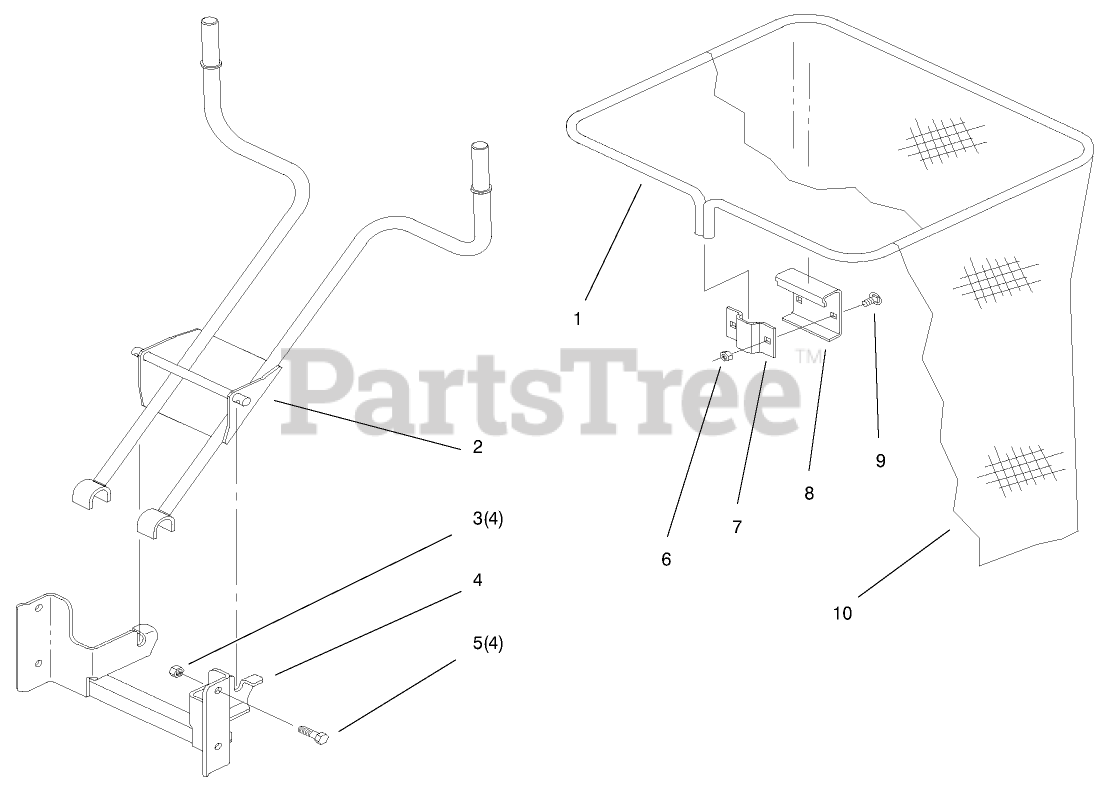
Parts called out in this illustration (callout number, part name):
1	FRAME-BAG
2	Bracket-Quick Attach
3	NUT-LOCK, NI
4	Support-Bagger
5	SCREW-HH
6	NUT-LOCK, NI
8	HANGER-BAG
9	BOLT-CARR
10	BAG-DEPTH
11	PIN-COTTER, HAIR
